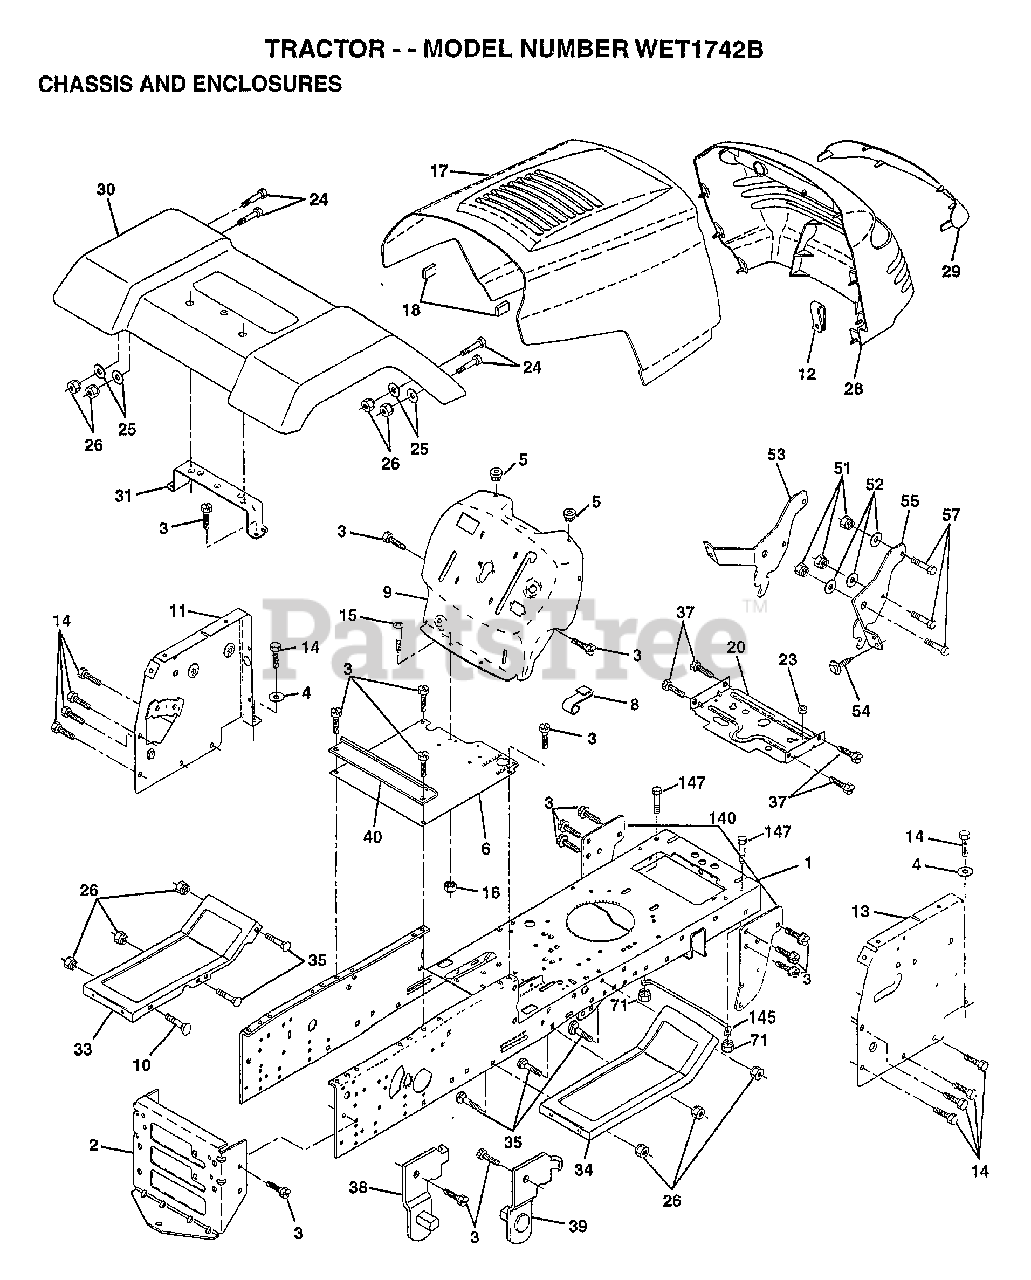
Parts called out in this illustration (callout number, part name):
1	CHASSIS ASM
3	SCREW
4	WASHER
5	BUMPER-HOOD/DASH
6	SADDLE
8	"CLIP,INSULATOR"
9	DASH.SILKSCREENED
11	"PANEL-DASH,LH"
12	CLIP.TINNERMAN
14	SCREW LT
15	SCREW
20	"PLATE-MTG,BATT/FU"
24	BOLT
25	WASHER
26	NUT
28	GRILLE-MS428
29	LENS GRILLE
30	FENDER
31	BRACKET SUPT FEND
33	FOOTREST.LH.LT/GT
34	FOOTREST.RH.LT/GT
35	BOLT
37	SCREW LT
38	BRACKET ASM LH
39	BRACKET ASM RH
40	SPACER FENDER LT
51	NUT
52	WASHER
53	BRACKET.GRILLE.LH
55	BRACKET.GRILLE.RH
140	BRKT SUSPENSION
145	"ROD POVOT,CHASSIS"
147	BOLT LT
